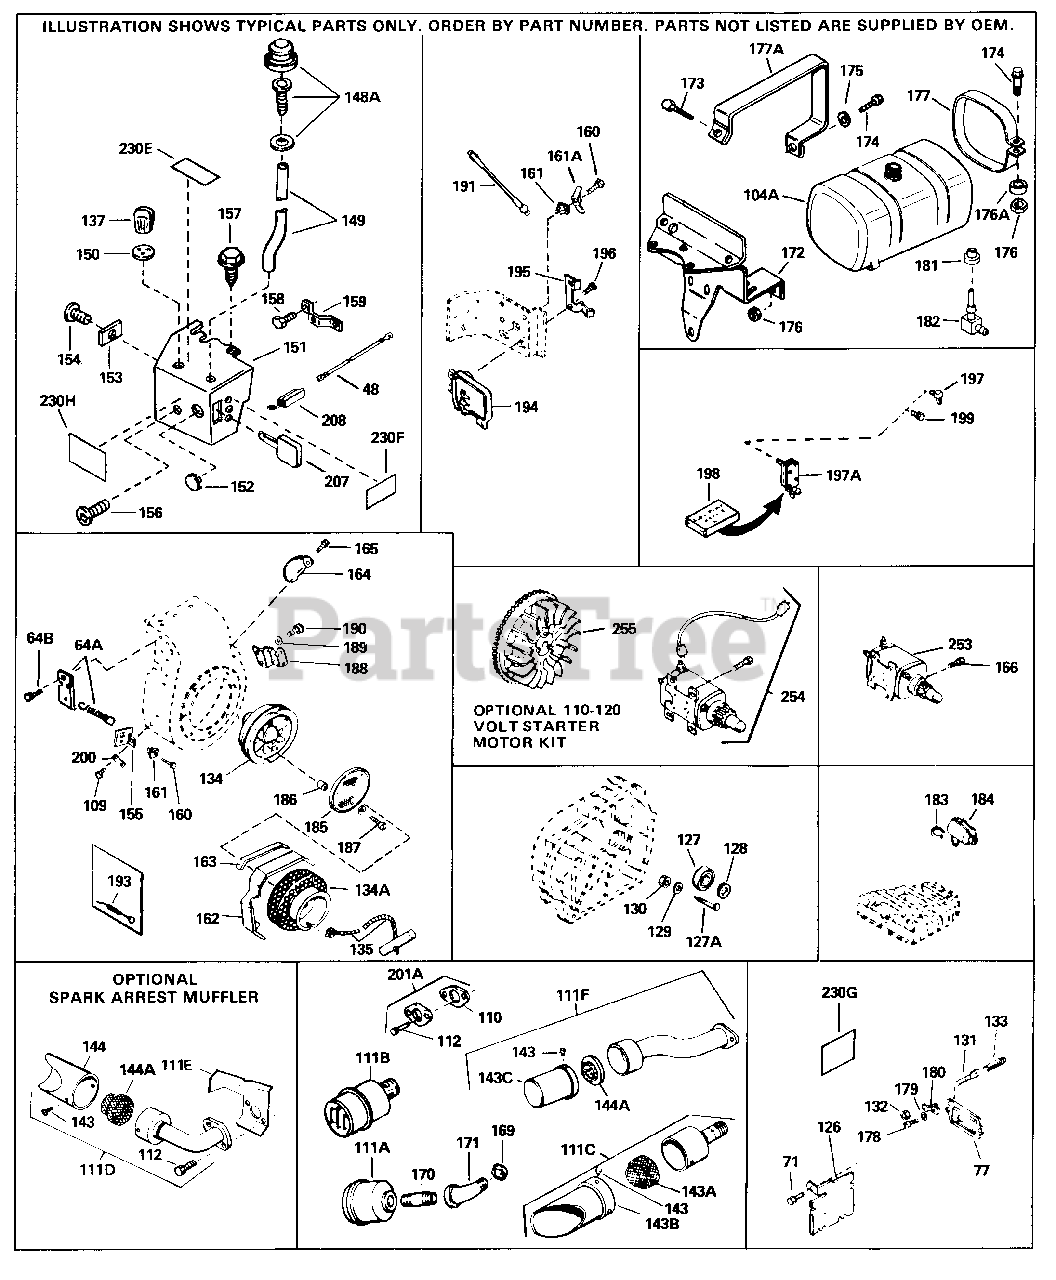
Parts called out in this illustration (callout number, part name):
35	Spool, Governor
48	Ground Wire
77	Valve Cover
109	Screw, T-40, 5/16-24 x 21/32"
110	* Gasket, Exhaust flange
111C	Opt.Spark Arrest Muf. Incl. 143,143A, 1 43B
111D	Opt.Spark Arrest Muf. Incl. 112,143,1 4 4,144A
111E	Deflector, Exhaust (Optional)
112	Screw, 5/16-18 x 3/4"
143	Screw, 8-18 x 3/8" (Use as required)
143A	Screen, Muffler (Use as required)
143B	Cover & tube, Muffler Use as require d
144	Cover & Tube, Muffler Use as require d
144A	Screen, Muffler (Use as required)
148A	Primer Assy.
149	Line, Primer
151	Cover, Carburetor
153	Nut, "U" Clip
154	Screw, 8-32 x 3/8"
155	Bracket, Grommet mounting
156	Screw, 8-32 x 5/16"
157	Screw, 10-32 x 1/2"
158	Screw, 10-32 x 1/2"
159	Bracket, Choke
160	Screw, 8-32 x 3/8"
161	Breather Tube Grommet
162	Guard, Starter
163	Seal, Snow Guard
164	Cover, Starter bubble
165	Screw, 8-32 x 3/8"
167	Deflector, Exhaust
201A	Muffler Adapter Kit (Incl. 110,112) A s req.
230F	Decal, Warning
254	Starter Motor Kit (110-120 volt) This 110-120 volt starter motor kit may h ave been added to this engine. It can be added only if cylinder hasdrilled and tapped starter mounting bosses a nd a ring gear flywheel (see#255). R efer to service number st
255	Flywheel (Ring gear flywheel required on engines using 110-120 volt starter motor kits listed above) (Used on St d. point ignition before 1982)
255	Flywheel (Ring gear flywheel required on engines using 110-120 volt starter motor kits listed above) (Used on St d. point ignition 1982 or later)
255	Flywheel (Minimum ring gear flywheel required on engines using 110-120 vol t starter motor kits listed above) (U sed on solid state external ignition)
